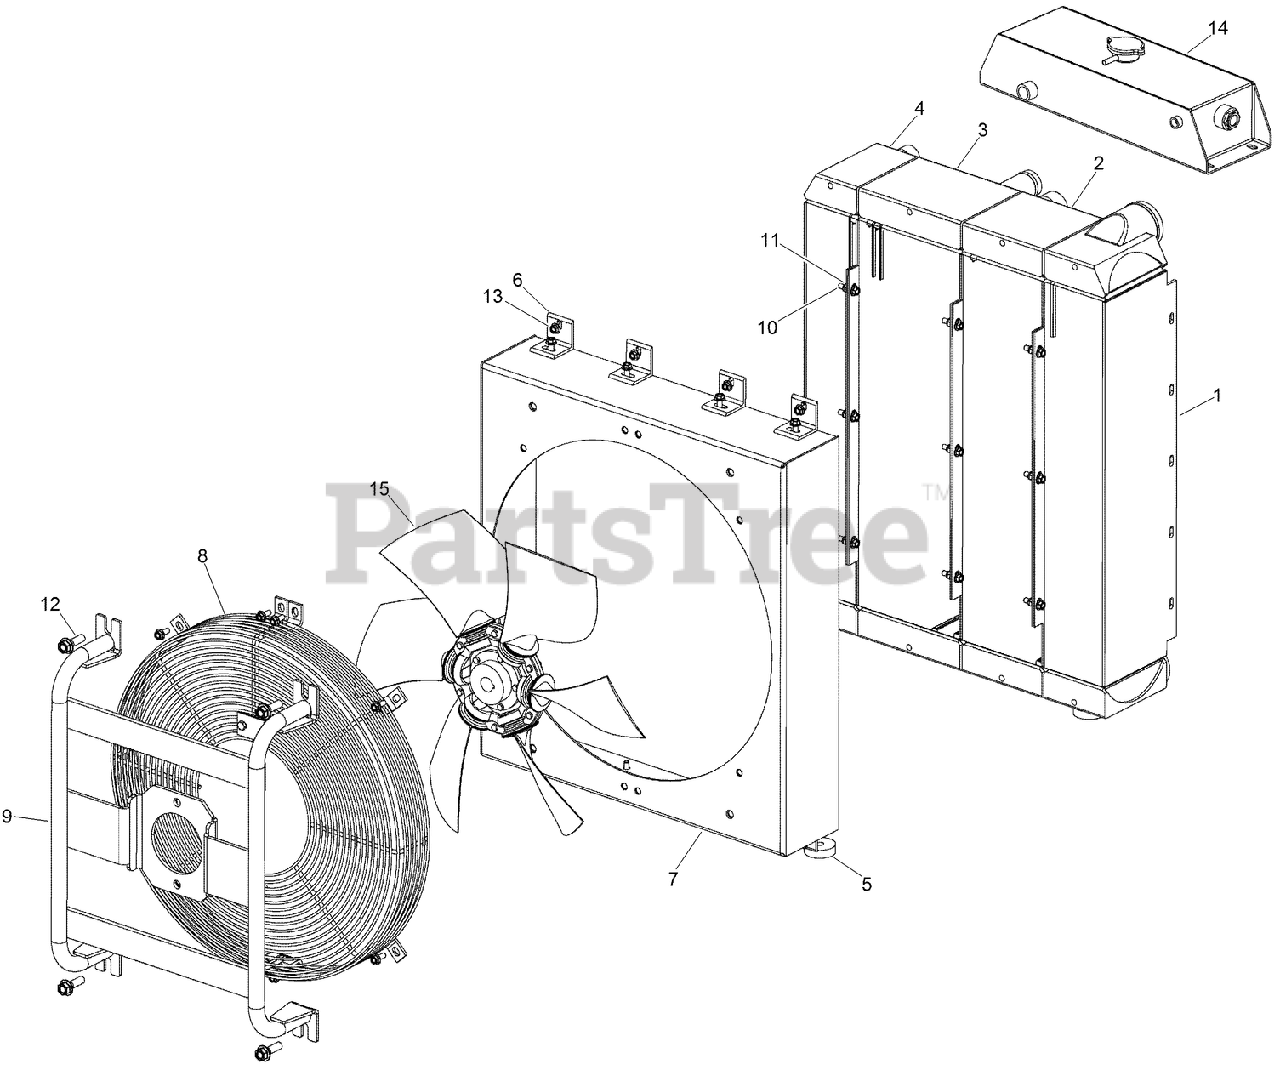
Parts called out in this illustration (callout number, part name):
1	COOLER - Charge Air
2	COOLER - Oil
3	COOLER - Radiator
4	COOLER - Transmission Oil
5	PLATE - Mounting
6	ANGLE - Bracket
7	WELDMENT - Fan Shroud
8	GUARD-FAN, 22 INCH
9	MOUNT - Motor, Cooling Package
10	SCREW, METRIC FLANGE FULL - M8 x 25
11	NUT-TORQUE, PREVAILING
13	SCREW, METRIC FLANGE w/BODY - M8 x 20
14	TANK-FILL/SURGE
15	OBS FAN-COOLING, 22IN
